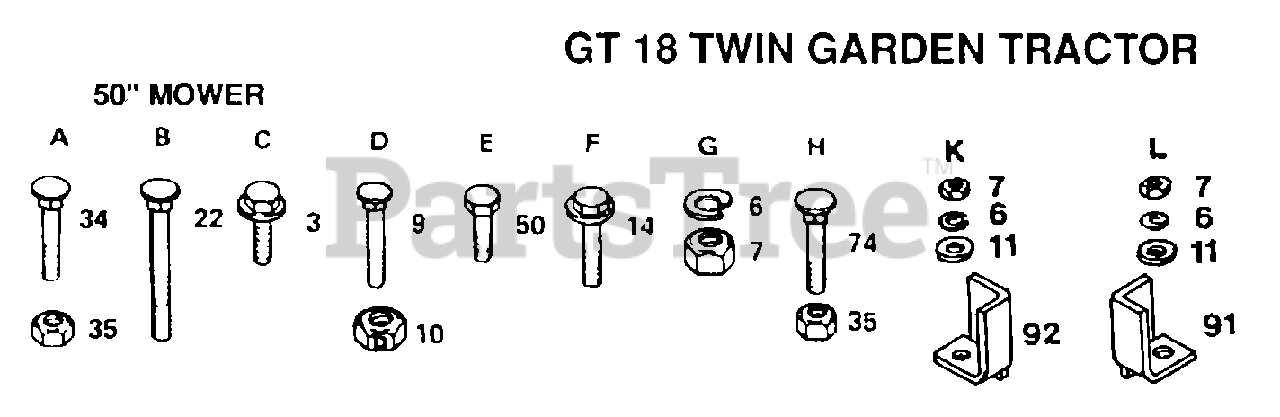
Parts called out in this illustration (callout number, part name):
3	SCREW LT
6	LOCKWASHER
7	NUT.HEX.5/16-18
9	BOLT
11	WASHER
14	SCREW
22	BOLT
34	BOLT
50	BOLT
74	BOLT
91	BRACKET RH M
92	BRACKET T
